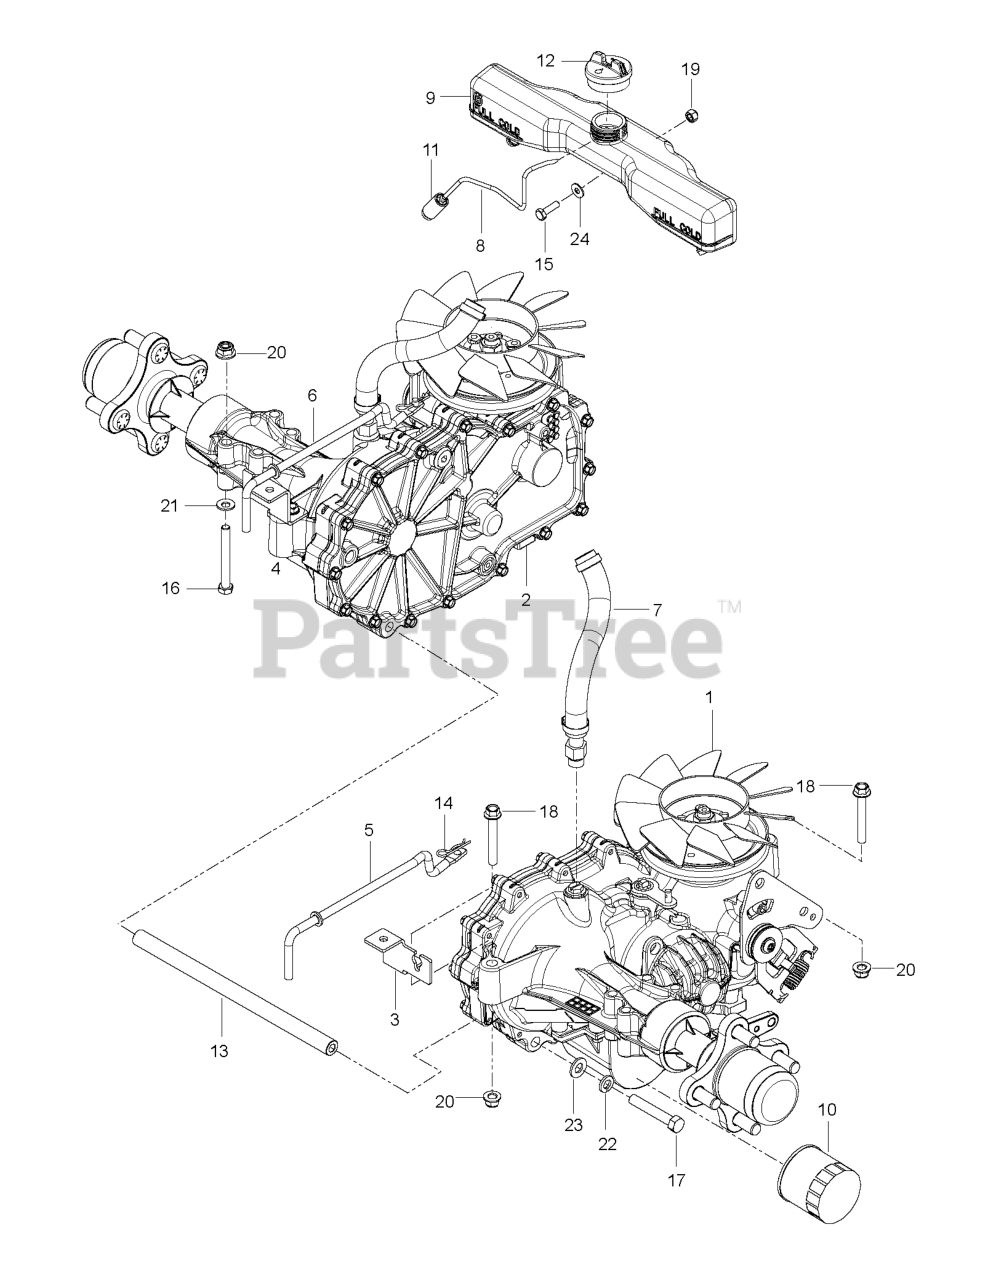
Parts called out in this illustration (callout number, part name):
1	HG_TRANS ZT-3100 RT
2	HG_TRANS ZT-3100 LT
3	BRACKET TRANS, RT BLACK MS-431
4	BRACKET TRANS, LT BLACK MS-431
5	LINKAGE, LEFT BYPASS
6	LINKAGE, RIGHT BYPASS
7	HOSE ASSY, EXPANSION
9	TANK EXPANSION W/CAP
10	HG_FILTER, ZT4800 52114
11	FUEL PICK-UP ASSY
12	CAP EXPANSION W/SEAL
13	TUBE, SPACER, 3400
14	HAIRPIN #2
15	HCS 1/4-20X7/8 GR5
17	HCS 3/8-16X2-1/4 LOC PATCH GR8
18	HHFS 5/16-18 X 2.25 GD 5
19	NUT.1/4-20.HEX.NYLOC.ZD
20	5/16-18 NYLOC FLANGE NUT
21	WASHER
22	SLW 3/8 STD
23	WASHER 3/8 SAE FLAT
24	WASHER 1/4 SAE
